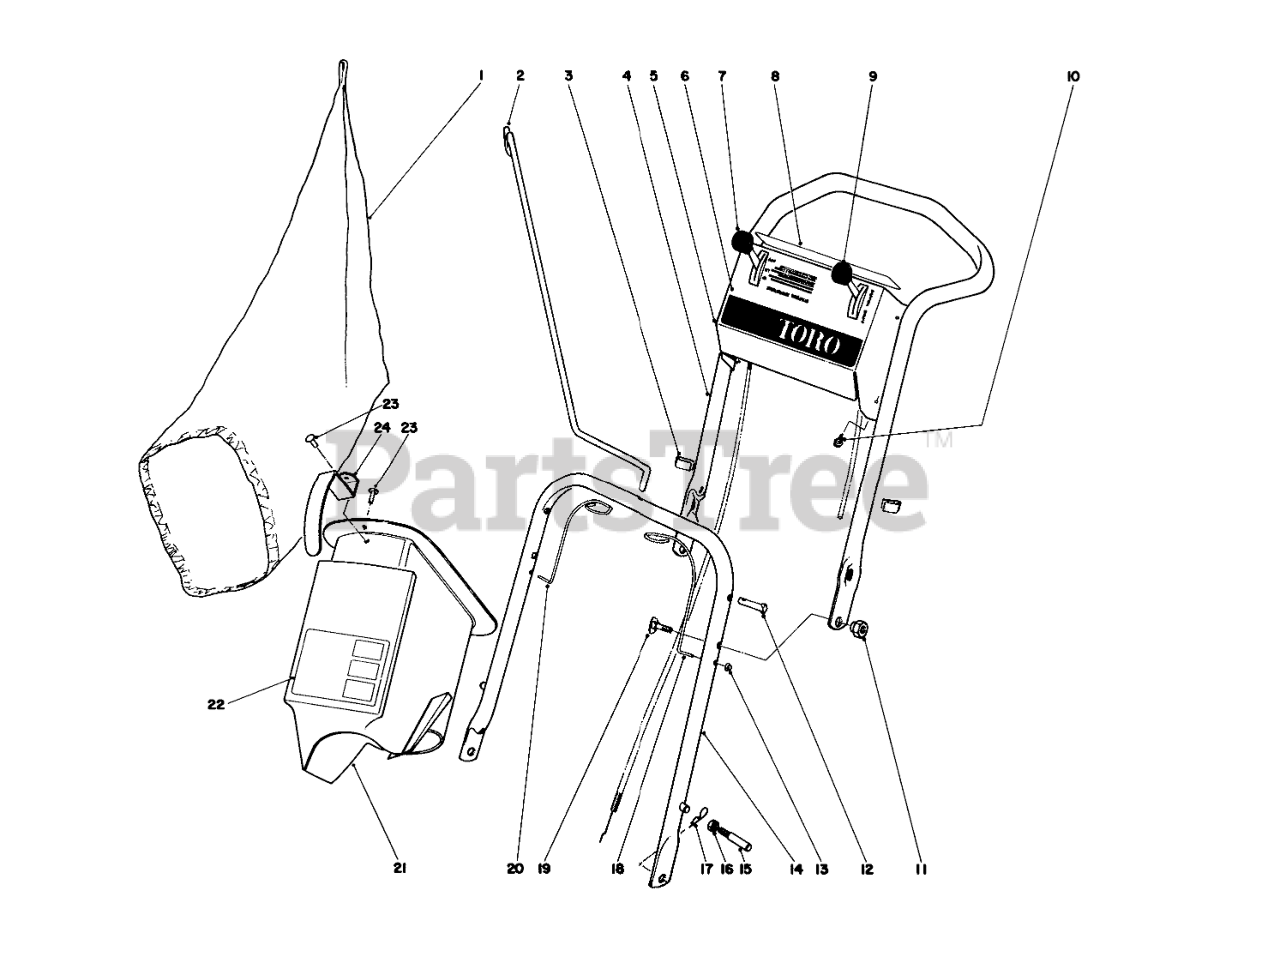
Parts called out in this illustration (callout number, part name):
1	BAG REPLACMNT44-0540
2	Bag Rod
4	Upper Handle
5	Control Plate
6	Decal Control Plate
7	Control Throttle
8	Decal, Safety
9	Traction Control
10	SCREW-HWHTF
11	Pivot Nut
12	Latch Pin
14	Lower Handle
15	HANDLE PIN
16	Nut
17	PIN-COTTER, HAIR
18	Latch Spring L.H.
19	HANDLE SCREW
20	Latch Spring R.H.
21	Grass Chute (Incl. Ref. #22-24)
22	Decal Instructions
24	HANDLE-GRASS CHUTE
